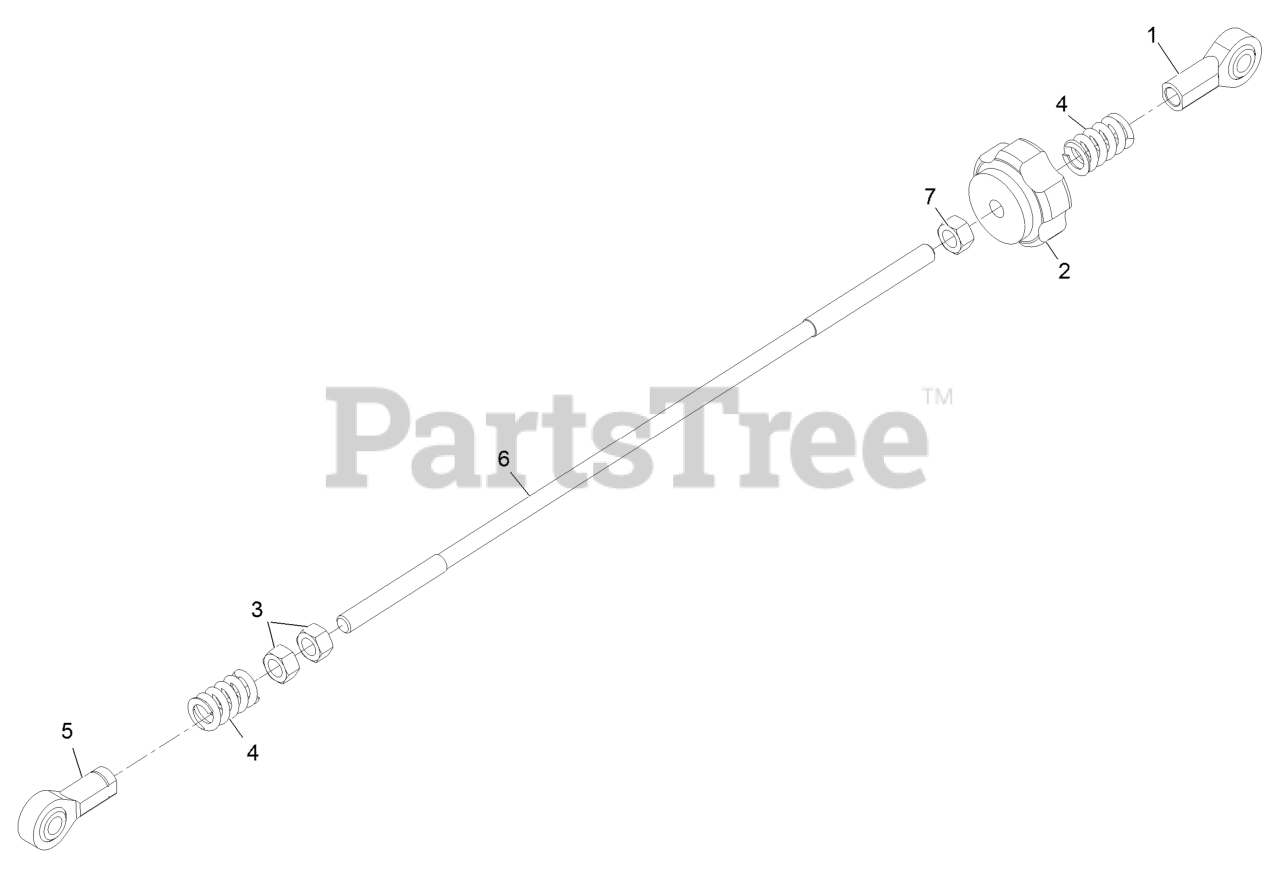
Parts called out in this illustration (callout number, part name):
1	BALLJOINT-RH
2	KNOB-TRACKING
4	SPRING-COMPRESSION
5	BALLJOINT-LH
6	LINK,TRACKING ROD XP
7	NUT-HEX
